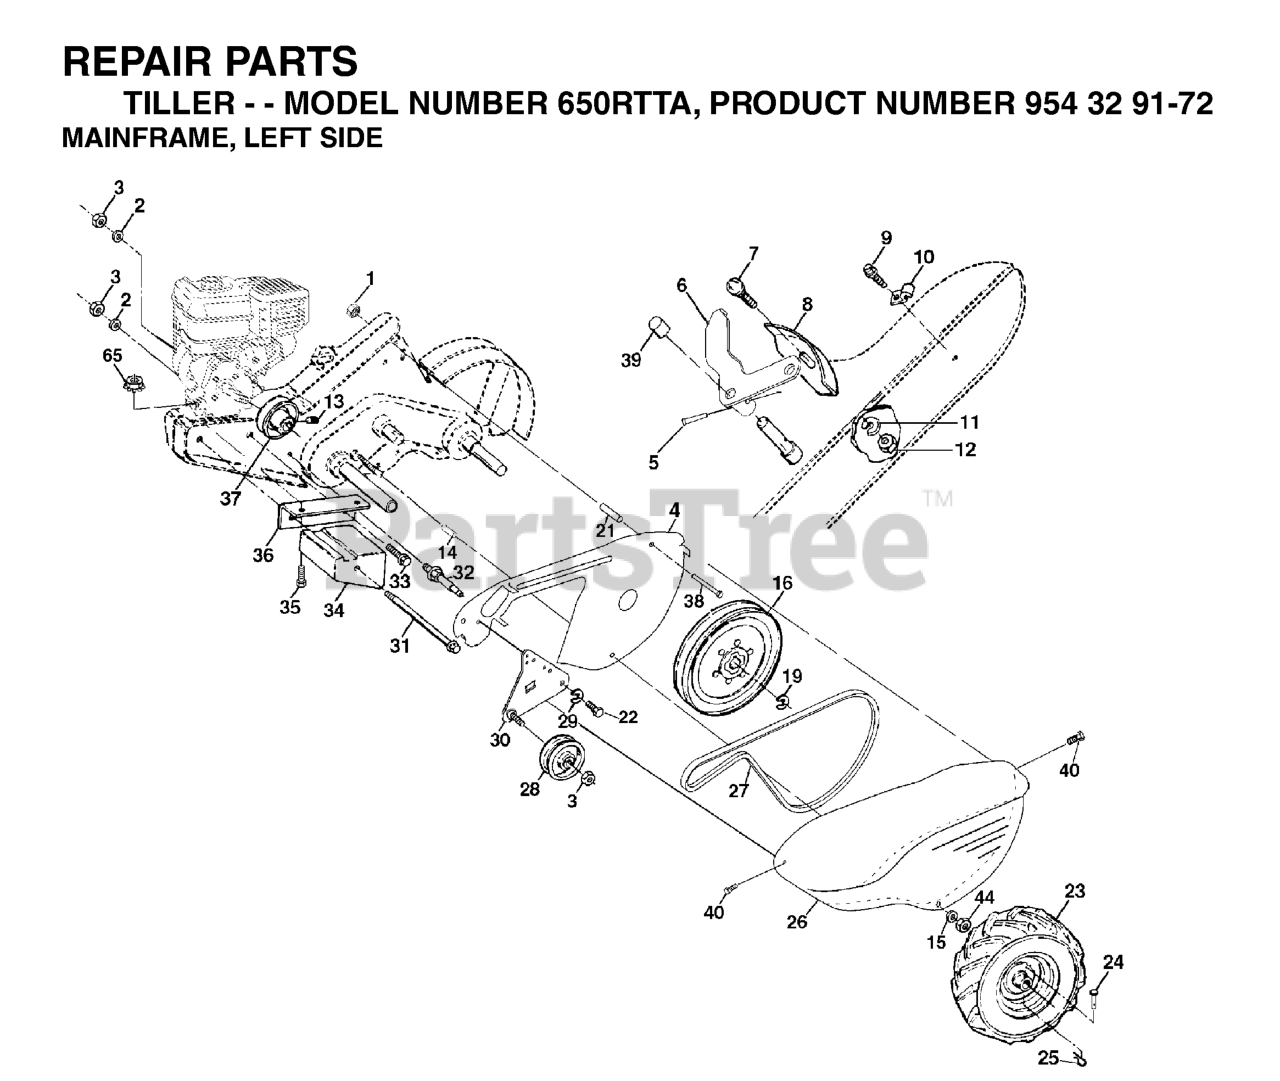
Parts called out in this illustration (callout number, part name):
1	NUT
2	WASHER, LOCK 3/8
3	NUT.HEX.3/8-16UNC
4	SHIELD
5	PIN.SPIROL.FLARED
6	LEVER ASM CRT
8	PANEL.INDICATOR.SHIFT.BLACK
9	TAPPING SCREW
10	CONDUIT.CLIP.PLATED
11	LOCKWASHER
12	NUT
14	SPACER CRT
15	WASHER
16	SHEAVE, TRANSMISSION
19	RETAINING RING LT
21	SPACER-SPLIT.327 X .42
23	TIRE.16X4-8.CHEVRON.TILLER
24	RIVET,DRILLED
25	RETAINER M
26	RP BELT GUARD
27	V-BELT
28	PULLEY-IDLER TI
30	BRACKET.ASM.IDLER.BLACK
31	BOLT.FIN.HEX.3/8-16UNC
32	SHIFT ARM CRT
33	BOLT
34	COUNTERWEIGHT.LH.CRT
35	BOLT
36	BRACKET LH CRT
37	RP.ENGINE PULLEY
38	BOLT
39	CAP.PLUNGER.BLACK
40	SCREW.HEX.WSH.SLT.#10-24X.50
44	NUT.71038.31-18.HEX.NYLOCK
65	LOCKNUT-FLANGE 5/16-18
